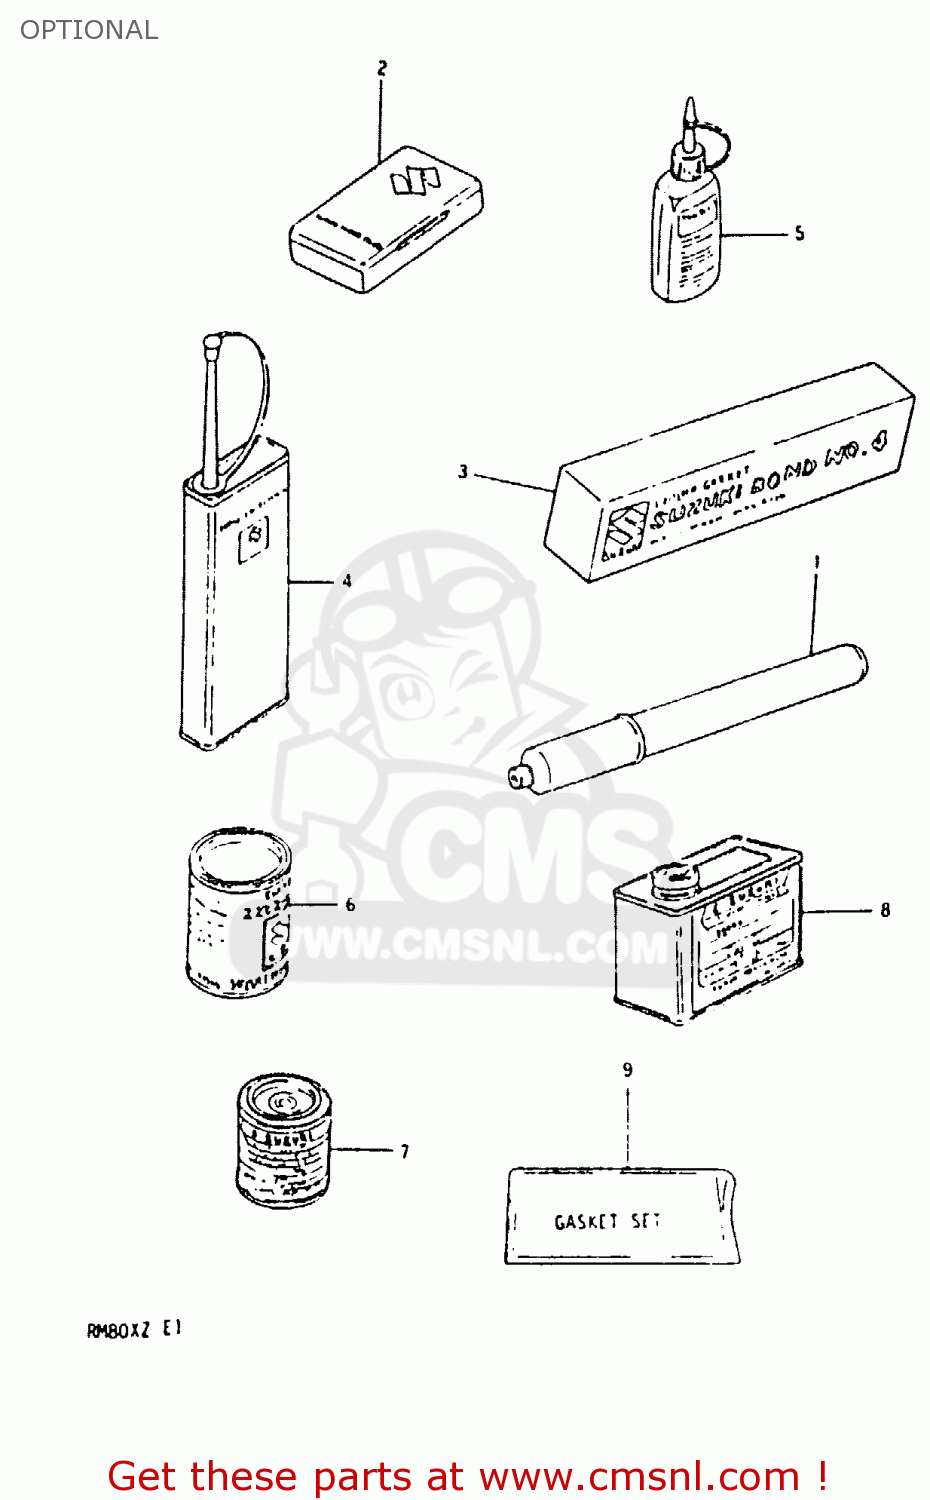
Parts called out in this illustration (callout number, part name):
1	INFLATOR, AIR
2	TUBE REPARING TOOL
3	BOND 1104
4	THREAD LOCK NO.1401 CLEAR 200G
5	THREAD LOCK NO.1303B PURPL 50G
6	GREASE(C)EP2 LITHIUM 150G
7	PAINT,BLACK
8	PAINT (BLACK)
9	GASKET SET
